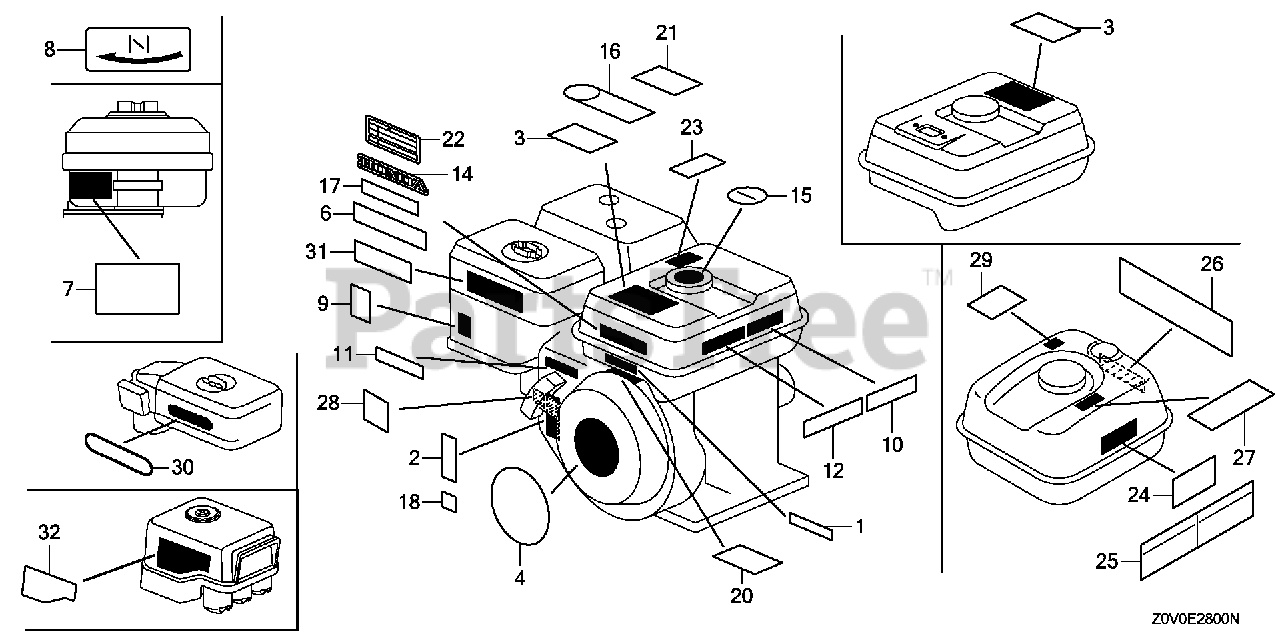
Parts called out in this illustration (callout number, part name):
4	EMBLEM (GX200)
9	MARK, CHOKE (GRAY)
11	MARK, THROTTLE INDICATION
18	LABEL, WARNING (NOT CERTIFIED FOR SALE)
21	MARK, OPERATOR CAUTION (ENGLISH)(MADE IN THAI)
21	MARK, OPERATOR CAUTION (FRENCH)(MADE IN THAI)
21	MARK, OPERATOR CAUTION (PICTOGRAPH)(MADE IN THAI)
23	MARK, EX. CAUTION (ENGLISH)
23	MARK, EX. CAUTION (FRENCH)
